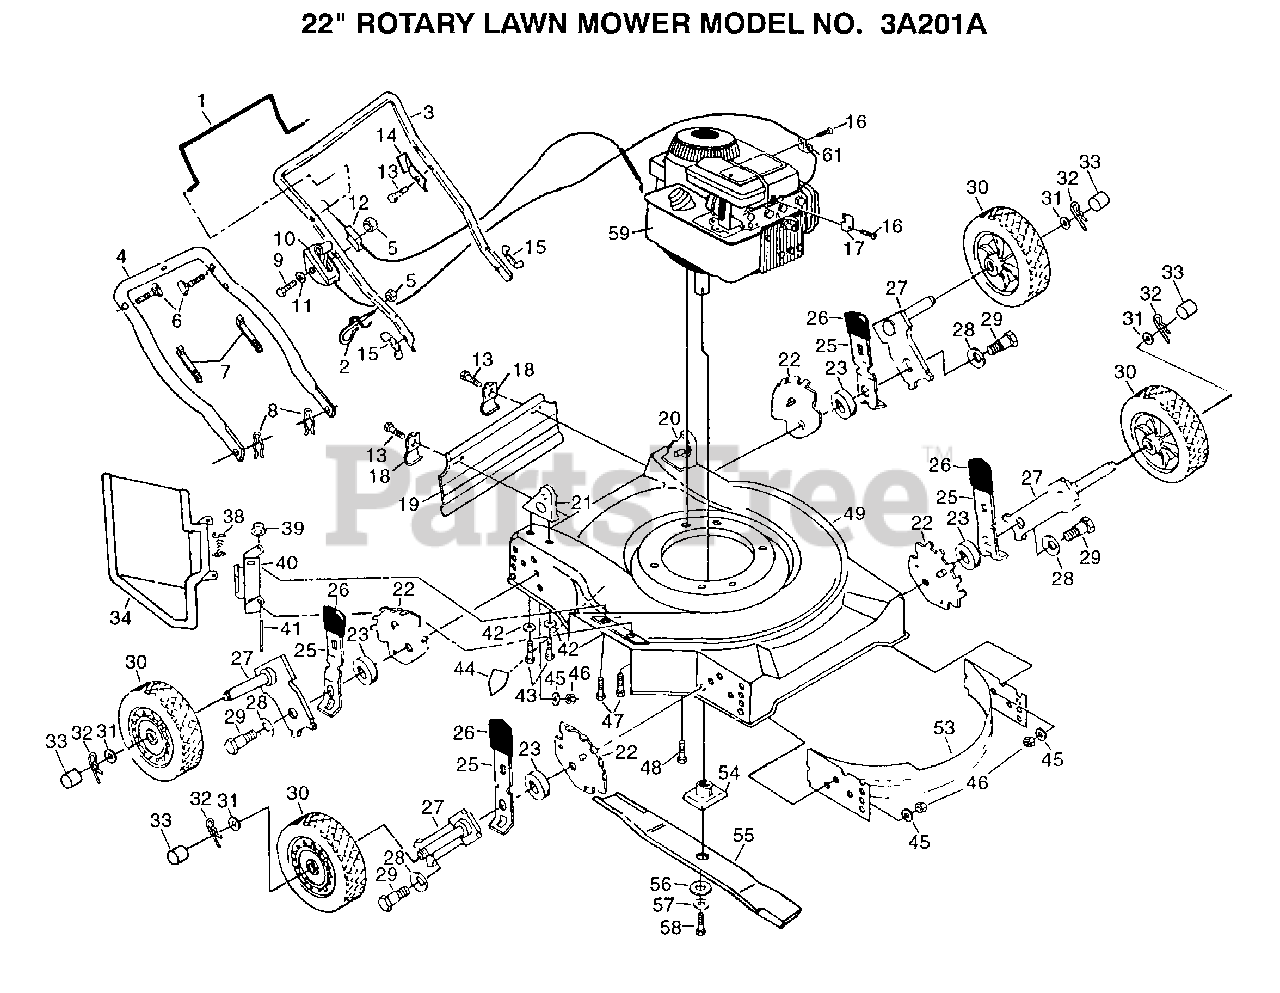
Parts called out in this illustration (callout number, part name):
1	CONTROL BAR PM
2	ROPE GUIDE
6	BOLT.HANDLE.LM
8	HAIRPIN COTTER
10	CONTROL THROTTLE
11	WASHER PM
12	"CABLE,ENG ZONE CO"
13	TAPPING SCREW
14	"BRKT,UPSTOP"
15	"NUT,WING PM"
16	SCREW PM
17	CABLE CLAMP
18	"BRKT,DEFL PM"
25	SPRING SELECTOR
26	KNOB PM
27	AXLE ARM
28	"WASHER, BELLEVIL."
30	WHEEL.ASM
31	WASHER
32	RETAINER CLIP PM
33	HUB CAP-PLASTIC
38	"SPRING,TORSION"
39	PUSH ON SPEED NUT
40	"BRKT,HSG"
41	"ROD,HINGE "
42	STEEL WASHER
43	SCREW
44	DECAL HYT
46	LOCKNUT PM
47	SCREW
48	SCREW
54	BLADE ADAPTOR
55	BLADE ADAPTOR
56	"WASHER,HARDEN"
57	LOCKWASHER
58	SCREW
61	"CLIP,CABLE"
